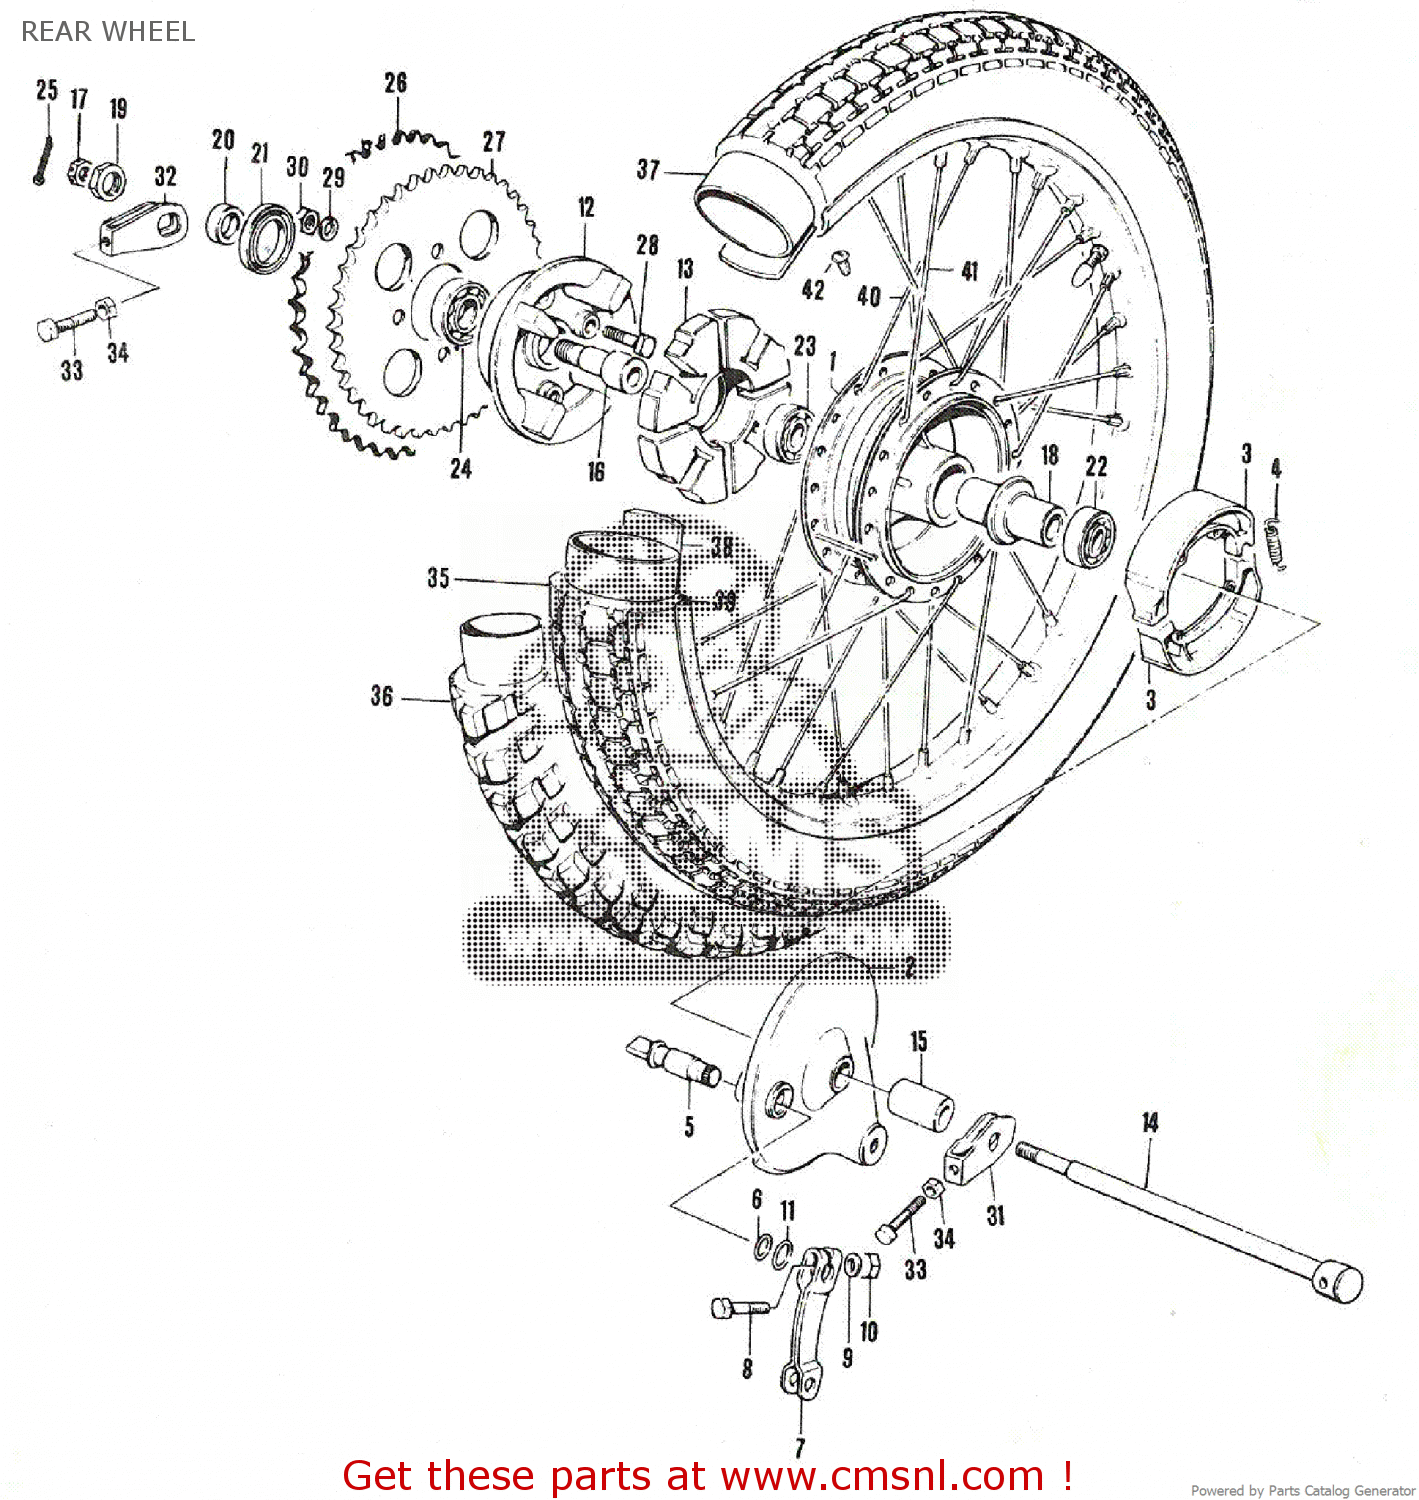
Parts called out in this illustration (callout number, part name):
1	HUB,REAR WHEEL
2	PANEL,REAR HUB
3	SHOE,BRAKE
4	SPRING(L:34)
5	CAM,FRONT BRAKE
6	O RING(D:2.5,ID:11.4)
7	LEVER,REAR BRAKE CAM
8	BOLT
9	WASHER
10	NUT
11	WASHER(12.5X20X1)
12	DRUM,RR SPROCKET
13	CUSHION,REAR DRUM
14	AXLE,RR
15	SPACER(15.2X26X33)
16	SHAFT,RR SPROCKET DRUM
17	NUT 12MM
18	SPACER,REAR HUB BEARING
19	NUT
20	SPACER(20X28X13)
21	OIL SEAL
22	BEARING
23	BEARING
24	Bearing
25	PIN
27	SPROCKET,REAR
28	BOLT(8X33.5)
29	LOCK WASHER
30	NUT
31	ADJUSTER,CHAIN
32	ADJUSTER,CHAIN
33	BOLT(6X38)
34	NUT
36	TIRE
37	TUBE,INNER
38	PROTECTOR,INNER TUBE
39	RIM,REAR WHEEL
40	SPOKE SET,REAR WHEEL
41	SPOKE,RR WHEEL OUTER
42	NIPPLE,SPOKE
